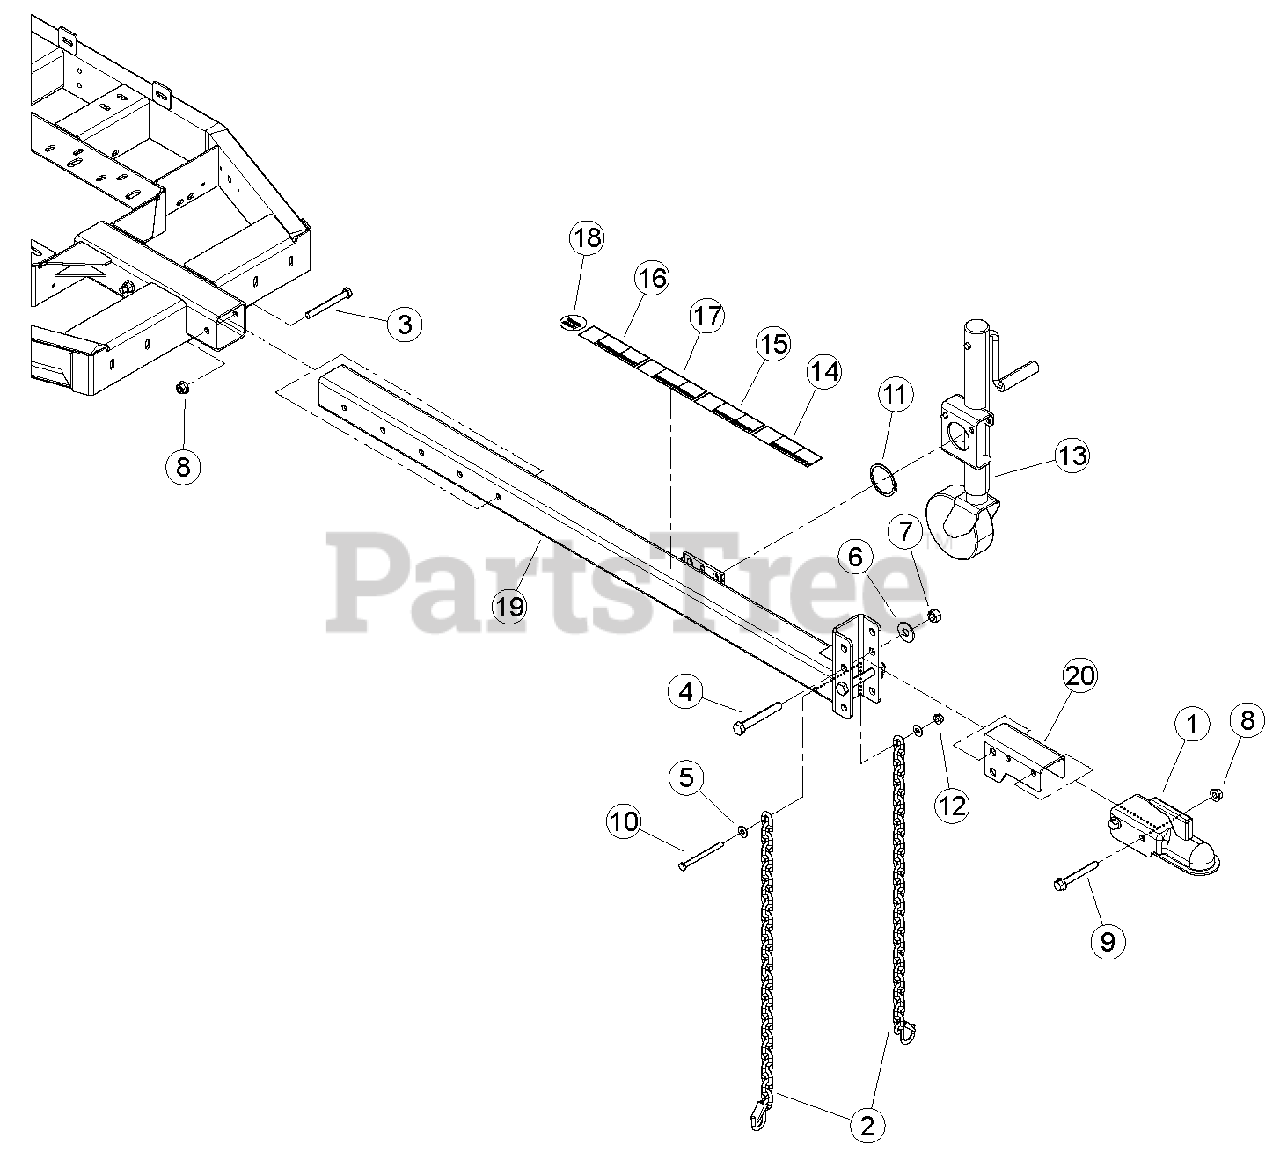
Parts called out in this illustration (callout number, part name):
1	COUPLER, 2 IN
2	CHAIN, SAFETY 5000 LB W/ LATCH
3	BOLT, 1/2 X 4-1/2" GR5 HHCS NC ZP
4	BOLT, 5/8 X 4-1/2 HEX HD G5 ZP
5	WASHER, 3/8" FLAT ZP
6	WASHER, 5/8" FLAT ZP
7	NUT, 5/8" CENTERLOCK ZP GR5
8	NUT, 1/2-13 NYLOCK FLANGE
9	BOLT, 1/2-13 X 4 HWH GR5 CZP
10	BOLT, 3/8 X 4-1/2" HHCS GR5 NC ZP
11	SNAP RING, 2-1/2 EXTERNAL
12	NUT, 3/8-16 NYLOCK FLANGE
13	JACK, PIVOTING W/ SWIVEL CASTOR
14	DECAL, SAFETY CHAINS
15	DECAL, TRAILER ELECTRICAL
16	DECAL, CHECK WHEELS
17	DECAL, SAFE COUPLING
18	DECAL, NATM COMPLIANCE
19	WELDMENT, HITCH POLE W/PLATE
20	MOUNT, COUPLER
